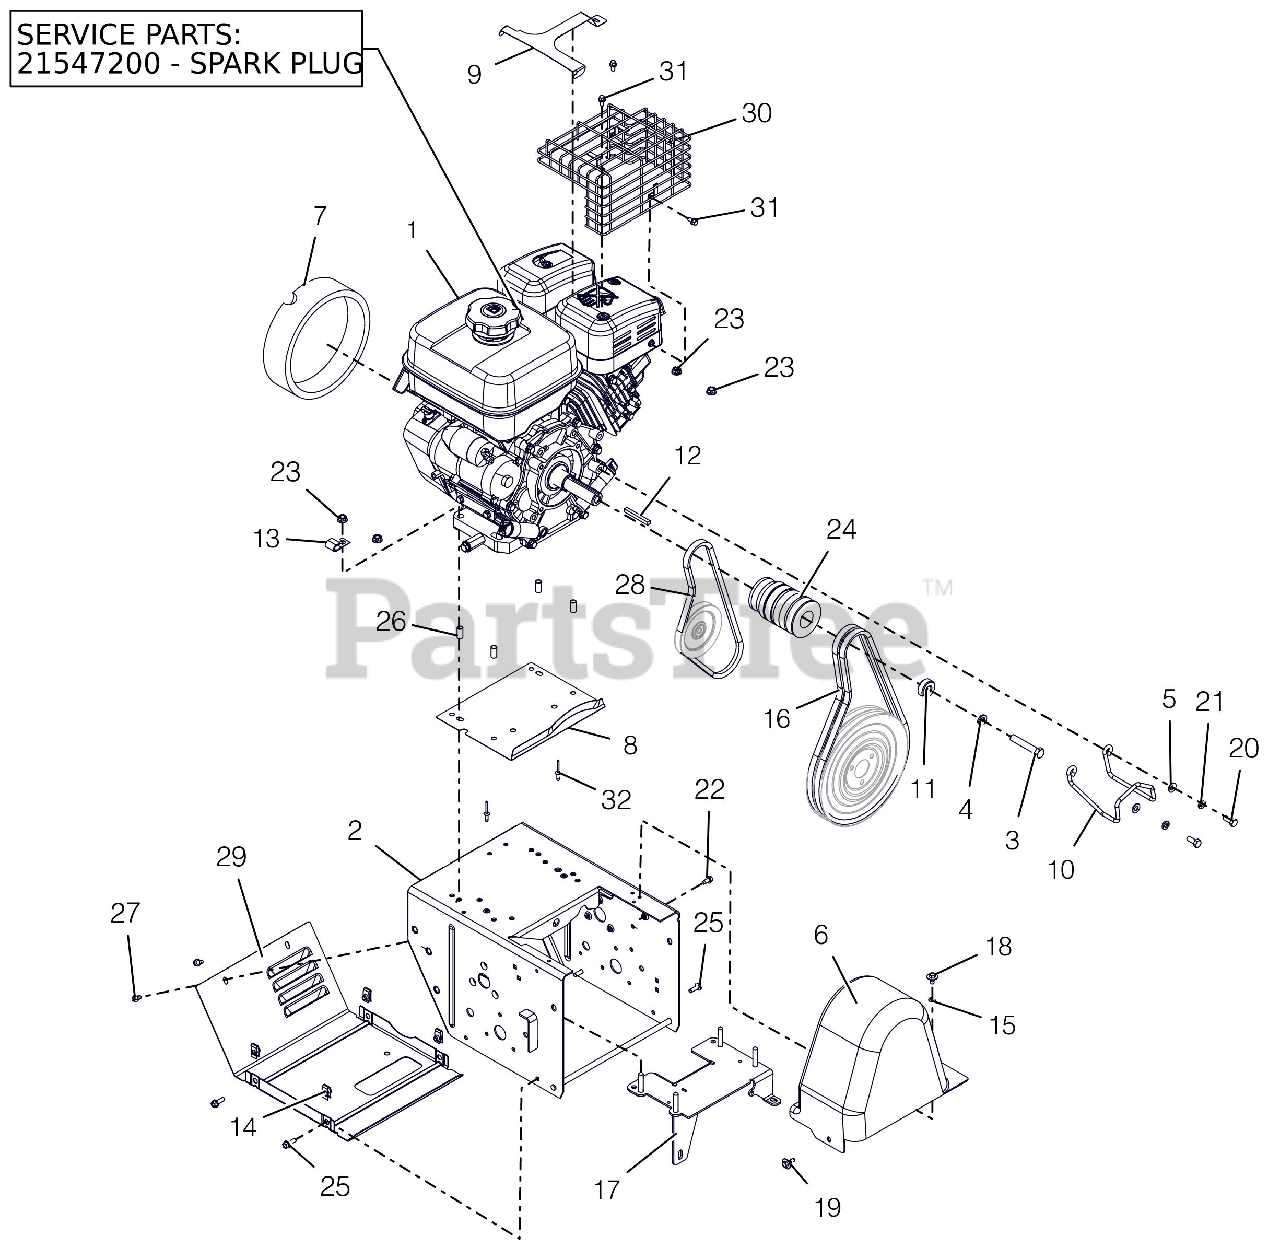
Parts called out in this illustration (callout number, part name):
1	ENGINE,SUBARU EX30 AS 12V
1	PLUG, SPARK SUBARU
2	FRAME, MAIN - PRO (WELDMENT)
3	BLT-HEX .44-20X2.50 GR5 YWZC
4	@WSHR-LK .44X.109 REG YWZC
5	@WSHR-FL-STL.344X.688X.065YWZC
6	COVER, BELT-TALL PRO
7	FOAM COVER, RECOIL-SUBARU
8	BAFFLE, WATER - LARGE BLOCK
9	GUARD, SNOW-SUBARU
10	FINGER, BELT
11	BSHG-SPACER .47X1.25X.50
12	KEY .25X.25X2.25
13	J-CLAMP
14	NUT-RTNR .25-20X.56
15	NUT-PUSH .25X.50 O.D.
16	V-BELT, HA-RAW EDGE (SET)
17	BRKT, HYDRO TRANS LG
18	SCR-TAP .25-20X.50 LGHWH TR YZ
19	SCR-TAP .25-20X.5 CAPTIVE
20	BLT-HEX .31-24X.75 YWZC GR5
21	WSHR-LK .312X.097 HVY YWZC
22	SCR-TAP .25-20X.50 HWH TR YWZ
23	@NUT-LK-CTR-FLG .31-18 YZ GR F
24	SHEAVE, COMBO HYDRO BRUSH
25	BLT-HEX .25-20X.75 HWH YZ GR5
26	BSHG-SLV .325X.400X.795
27	SCR-TAP .25-20X.50 HWH TR YWZ
28	V-BELT, 4L-WRAPPED
29	COVER, BOTTOM - VENTILATED
30	MUFFLER GUARD, SUB EX270JO930
31	BLT-SERHFWH M6X1.0X12 8.8 CZ
32	RVT-POP .187 YZ
